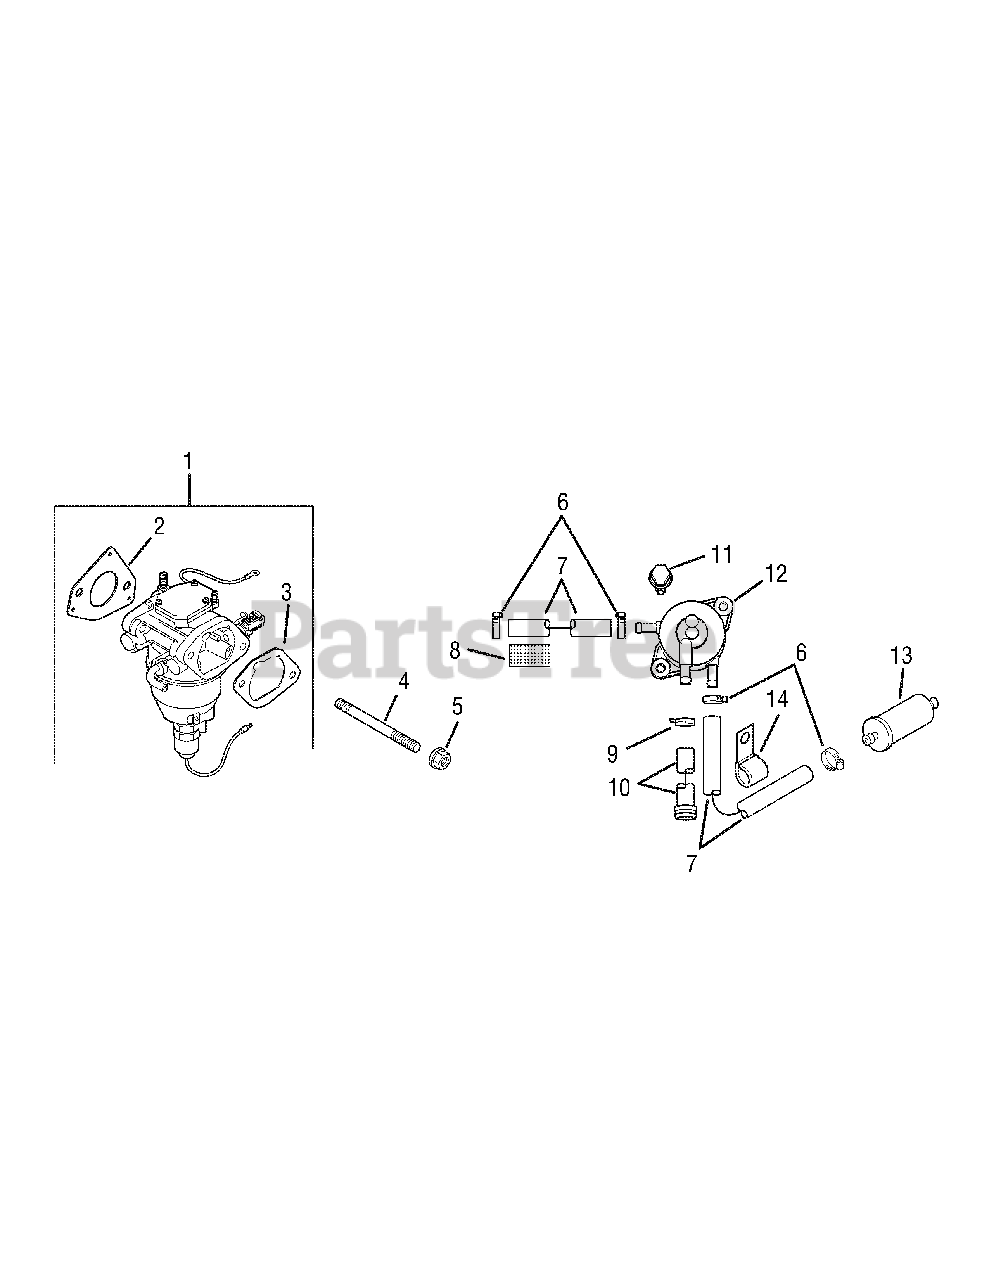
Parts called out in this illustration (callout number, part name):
1	Kit, carb. w/gaskets
2	Gasket, carburetor
3	Gasket, air cleaner base
4	Stud, carburetor
5	Nut, hex. flange M6x1.0
6	Clamp, hose
7	Line, fuel
8	Anti-Abrasion Sleeve
10	Hose, fuel pump
11	Screw, hex. cap M6x1.7x18
12	Pump, pulse fuel
13	Filter, fuel
